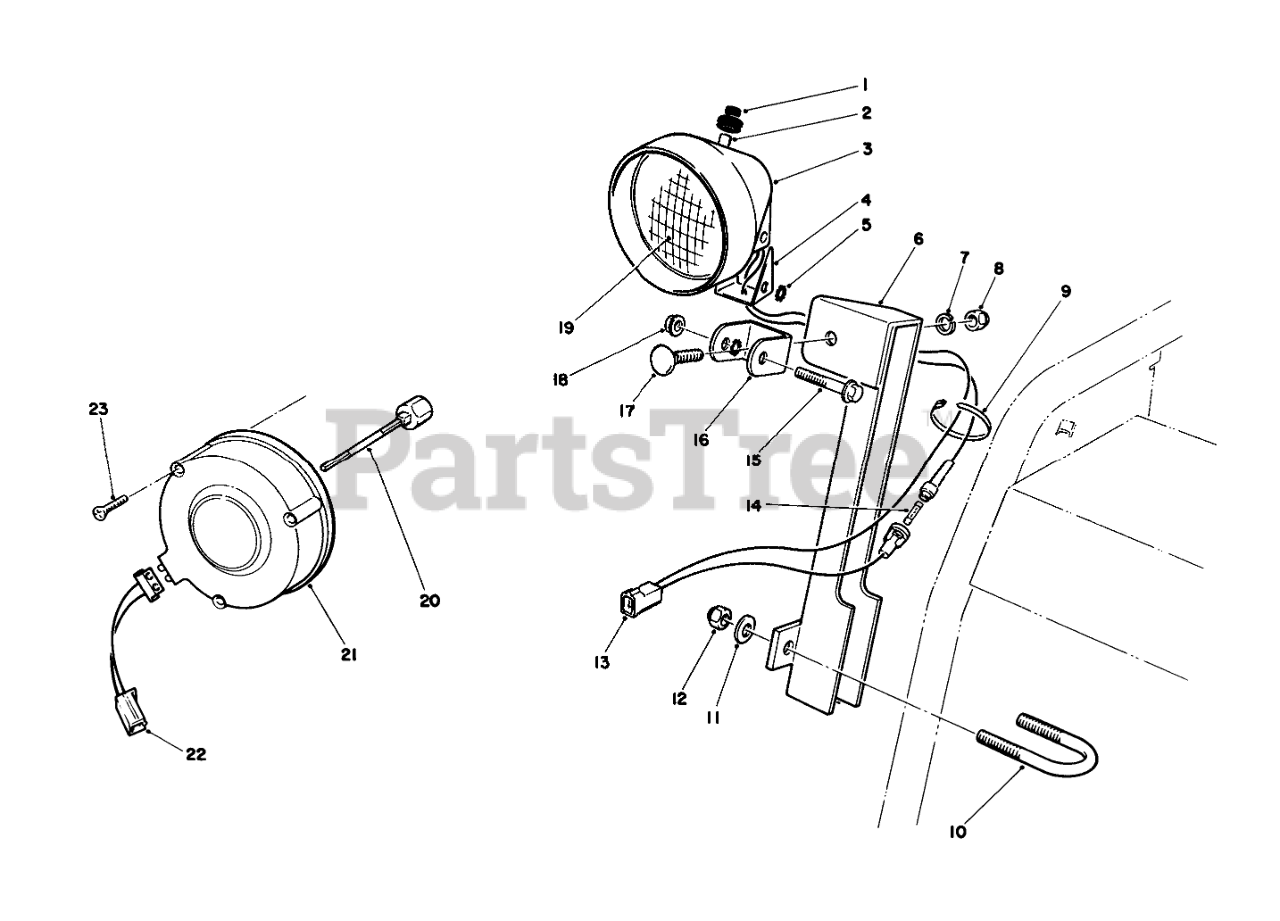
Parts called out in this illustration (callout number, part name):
2	SWITCH ASM
3	Bucket-Headlamp
4	TO BE DISCONTINED-NOT NEEDED ON PRODUCT
5	WASHER-LOCK
6	Mount-Lamp
7	WASHER-LOCK
8	NUT-HEX
9	TIE-CABLE
10	U-BOLT
11	WASHER-PLAIN
12	NUT-LOCK, NI
13	WIRE ASM
14	Fuse-7-1/2 Amp.
15	SCREW-HH
16	BRACKET
17	BOLT-CARR
18	NUT-HF
19	BEAM-SEALED
20	Shaft-Alternator, 3 Inch
21	Alternator
22	Connector-Wire
23	SELF TAP SCREW
